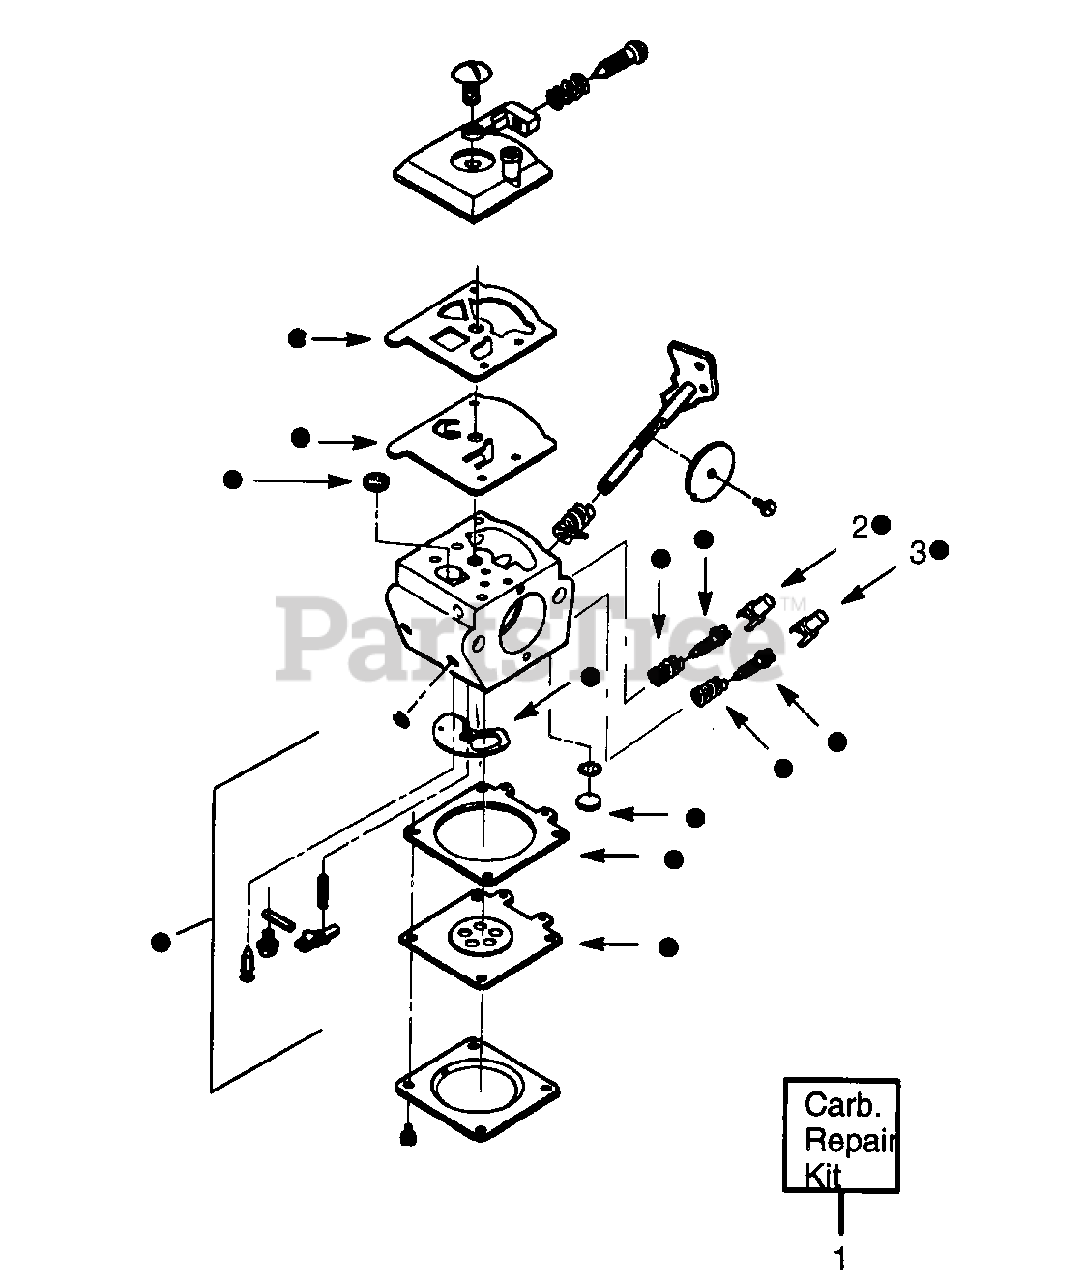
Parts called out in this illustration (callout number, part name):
1	Carburetor Repair Kit
2	Limiter Cap-Low
3	Limiter Cap-High
